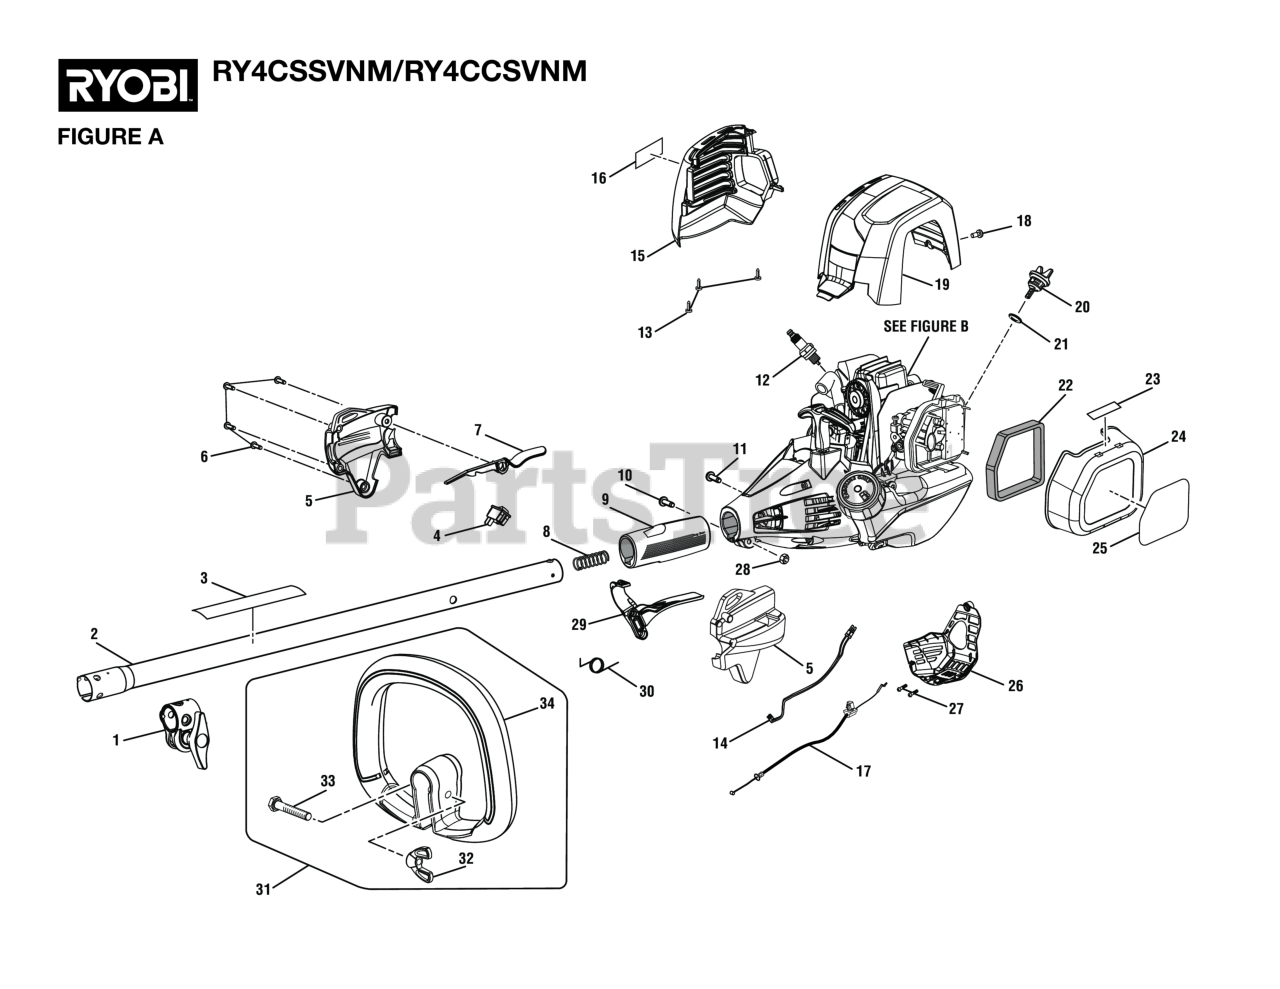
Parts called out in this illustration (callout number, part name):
1	Boom Clamp Assembly
2	Upper Boom Assembly
3	Warning Icon Label
4	Stop Switch (Momentary Contact)
5	Control Handle Assembly (Inc. Key No. 6)
6	Screw (M4 x 20 mm, T20 Torx Pan Hd. S.T.)
7	Trigger Lock
8	COMPRESSION SPRING
9	Rear Handle Grip
10	Screw (M6 x 20 mm, T27 Torx Button Hd.)
11	Screw (M4 x 8 mm, T25 Torx Pan Hd. T.F.)
12	Spark Plug (Champion RY4C)
13	Screw (M4 x 12 mm, T20 Torx Truss Hd.)
14	Lead Assembly
15	Muffler Housing (Inc. Key No. 16)
16	Warning Label (Combustion)
17	Throttle Cable
18	Shoulder Screw (M4 x 11 mm, T25 Torx Pan Hd.)
19	Top Cover
20	Oil Cap/Dipstick (Incl. key no. 12)
22	Air Filter
23	Choke Label
24	Air Filter Cover
25	Starting Label
26	CE Cover (Bottom Cover)
27	Screw (#6-19 x 1/2 in., Phillips Hd. T.F.)
28	Hex Nut (M6.3 x 1)
30	Torsion Spring (Throttle Trigger)
31	Front Handle Assembly
32	Wing Nut (1/4-20, Plastic)
33	Screw (1/4-20 x 40 mm, Cap Hex Hd.)
34	Front Handle
